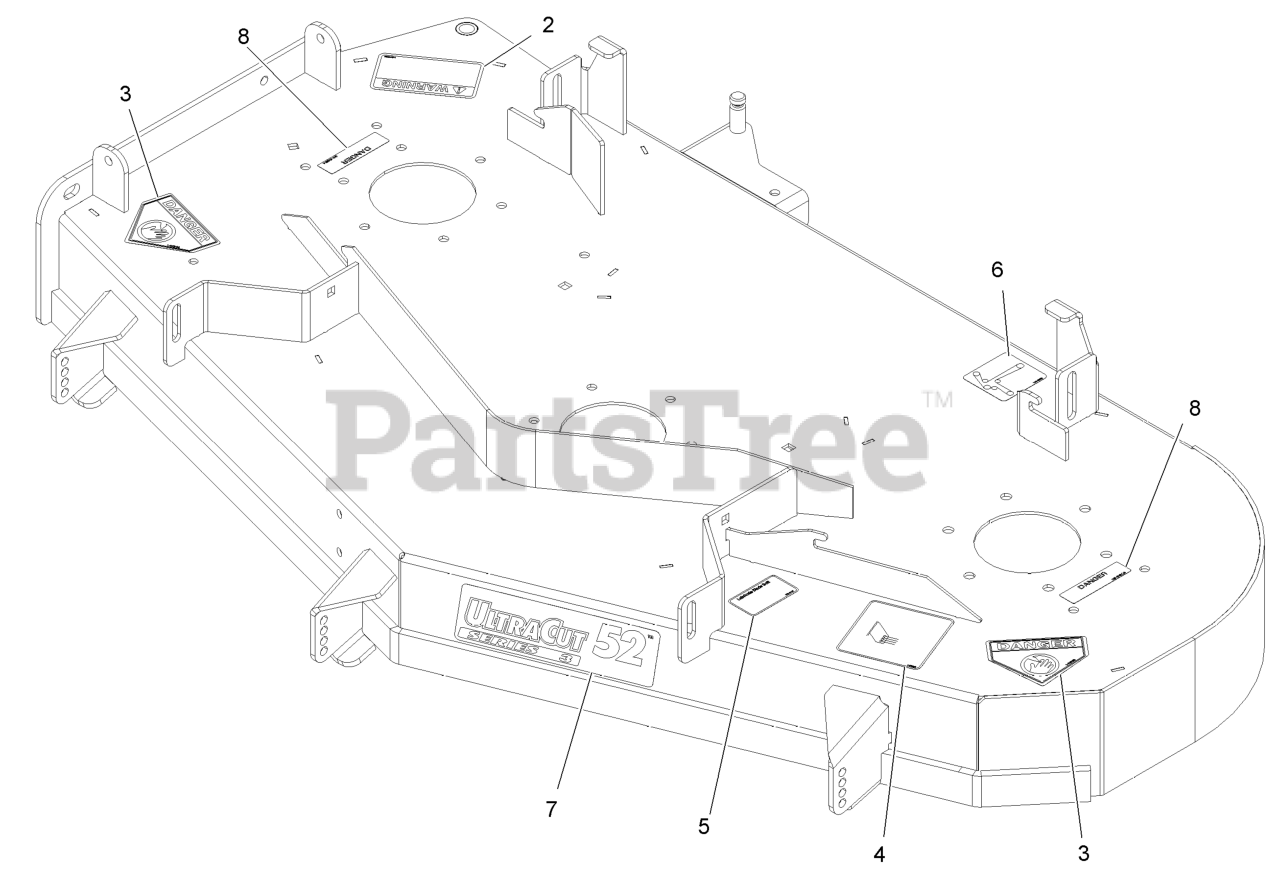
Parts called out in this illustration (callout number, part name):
2	DECAL-WARNING, DISCHARGE
3	DECAL-DANGER
4	DECAL,ANTISCALP
5	DECAL,BOLT TORQUE
6	DECAL-ROUTING, BELT
7	DECAL-ULTRACUT 52 SERIES
8	DECAL-COVER, MISSING
